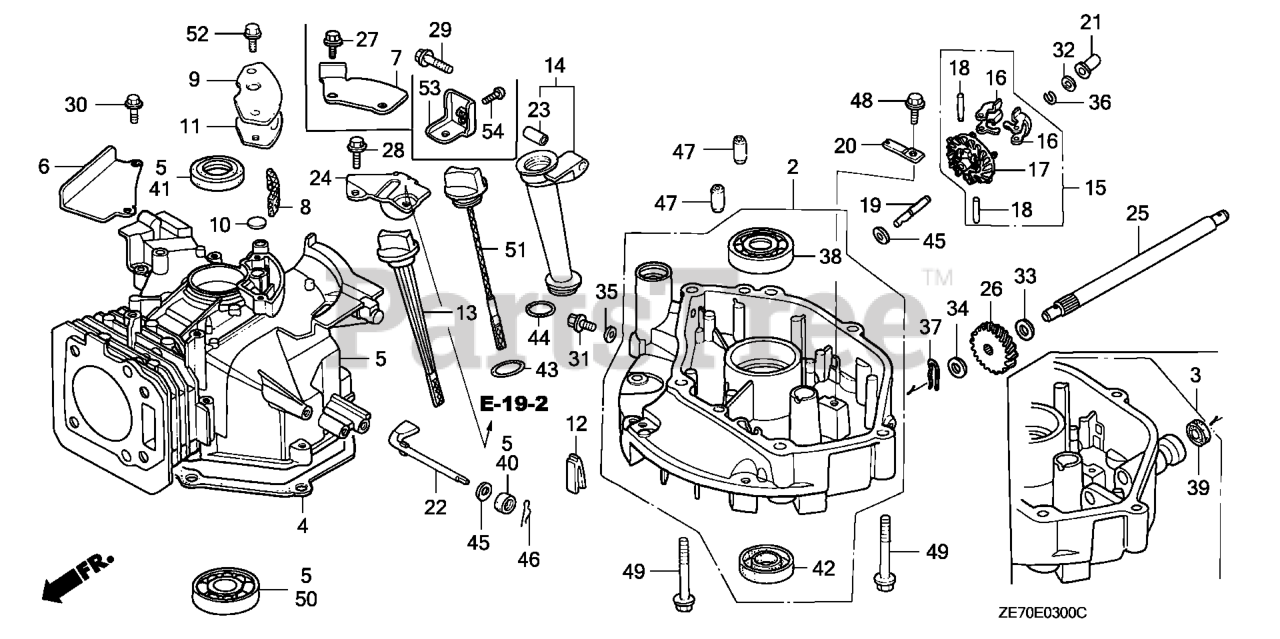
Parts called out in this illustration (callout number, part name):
2	PAN ASSY., OIL
4	GASKET, OIL PAN
5	CYLINDER ASSY.
6	PLATE, GUIDE
7	PLATE A, GUIDE
8	FILTER, BREATHER
9	COVER, BREATHER
10	VALVE, BREATHER
11	GASKET, BREATHER COVER
12	RUBBER, OIL RETURN
13	GAUGE, OIL LEVEL Use up to Engine SN 1257294.
14	EXTENSION, OIL FILLER (106MM)
15	GOVERNOR ASSY.
16	WEIGHT, GOVERNOR
17	HOLDER, GOVERNOR WEIGHT
18	PIN, GOVERNOR WEIGHT
19	SHAFT, GOVERNOR HOLDER
20	PLATE, GOVERNOR SHAFT HOLDER
21	SLIDER, GOVERNOR
22	SHAFT, GOVERNOR ARM
23	COLLAR, EXTENSION Use up to Engine SN 1257294.
27	BOLT, FLANGE (6X12) (CT200)
29	BOLT, FLANGE (6X32)
30	BOLT, FLANGE (6X20) (CT200)
31	BOLT, DRAIN PLUG
32	WASHER, THRUST (6MM)
35	WASHER, DRAIN PLUG (10.2MM)
36	CLIP, GOVERNOR HOLDER
40	OIL SEAL (6X11X4)
41	OIL SEAL (25X38X7)
41	OIL SEAL (25X38X7) (ARAI)
42	OIL SEAL (25.4X40X7)
43	O-RING (22.5X2.2) Use from Engine SN 1257295.
44	O-RING (26X2.7)
45	WASHER, PLAIN (6MM)
46	PIN, LOCK (8MM)
47	PIN A, DOWEL (8X14)
48	BOLT, FLANGE (6X12) Use from Engine SN 2086984.
49	BOLT, FLANGE (8X50)
50	BEARING, RADIAL BALL (6205)
52	BOLT, FLANGE (6X14)
